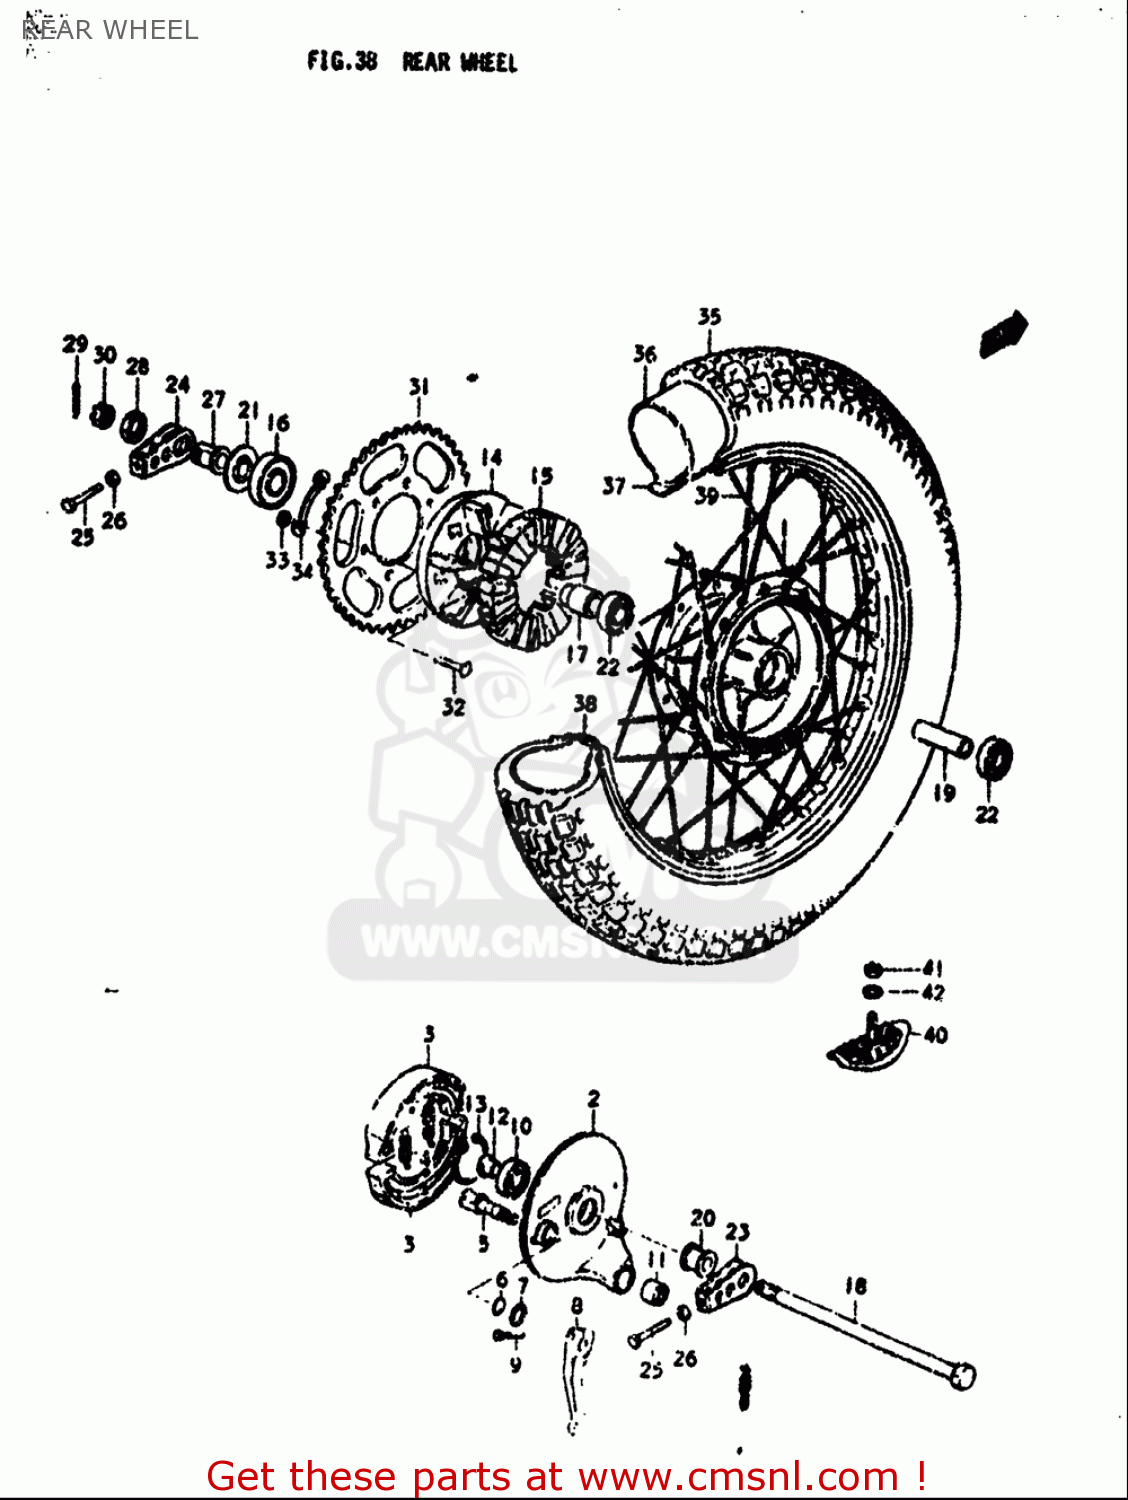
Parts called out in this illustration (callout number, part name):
3	SHOE SET,BRAKE (NAS)
4	SPRING
5	CAM,BRAKE
6	O RING(D:2.4,ID:14.8)
7	WASHER(15.5X24X1.6)
9	BOLT
10	BEARING
11	BUSH
13	CIRCLIP
15	CUSHION,REAR DRUM
16	BEARING
18	AXLE,REAR
21	SPACER,REAR AXLE,RIGHT
22	BEARING
23	ADJUSTER,CHAIN
24	ADJUSTER,CHAIN
25	BOLT(8X50)
26	NUT
27	SPACER,CHAIN ADJUSTER
28	NUT
29	PIN 30X40
30	NUT
31	SPROCKET,RR
32	BOLT(8X33.5)
33	NUT
34	WASHER
36	TUBE,INNER
37	PROTECTOR,INNER TUBE
39	SPOKE SET,RR
40	STOPPER,BEAD(1.85)
41	NUT
42	WASHER
